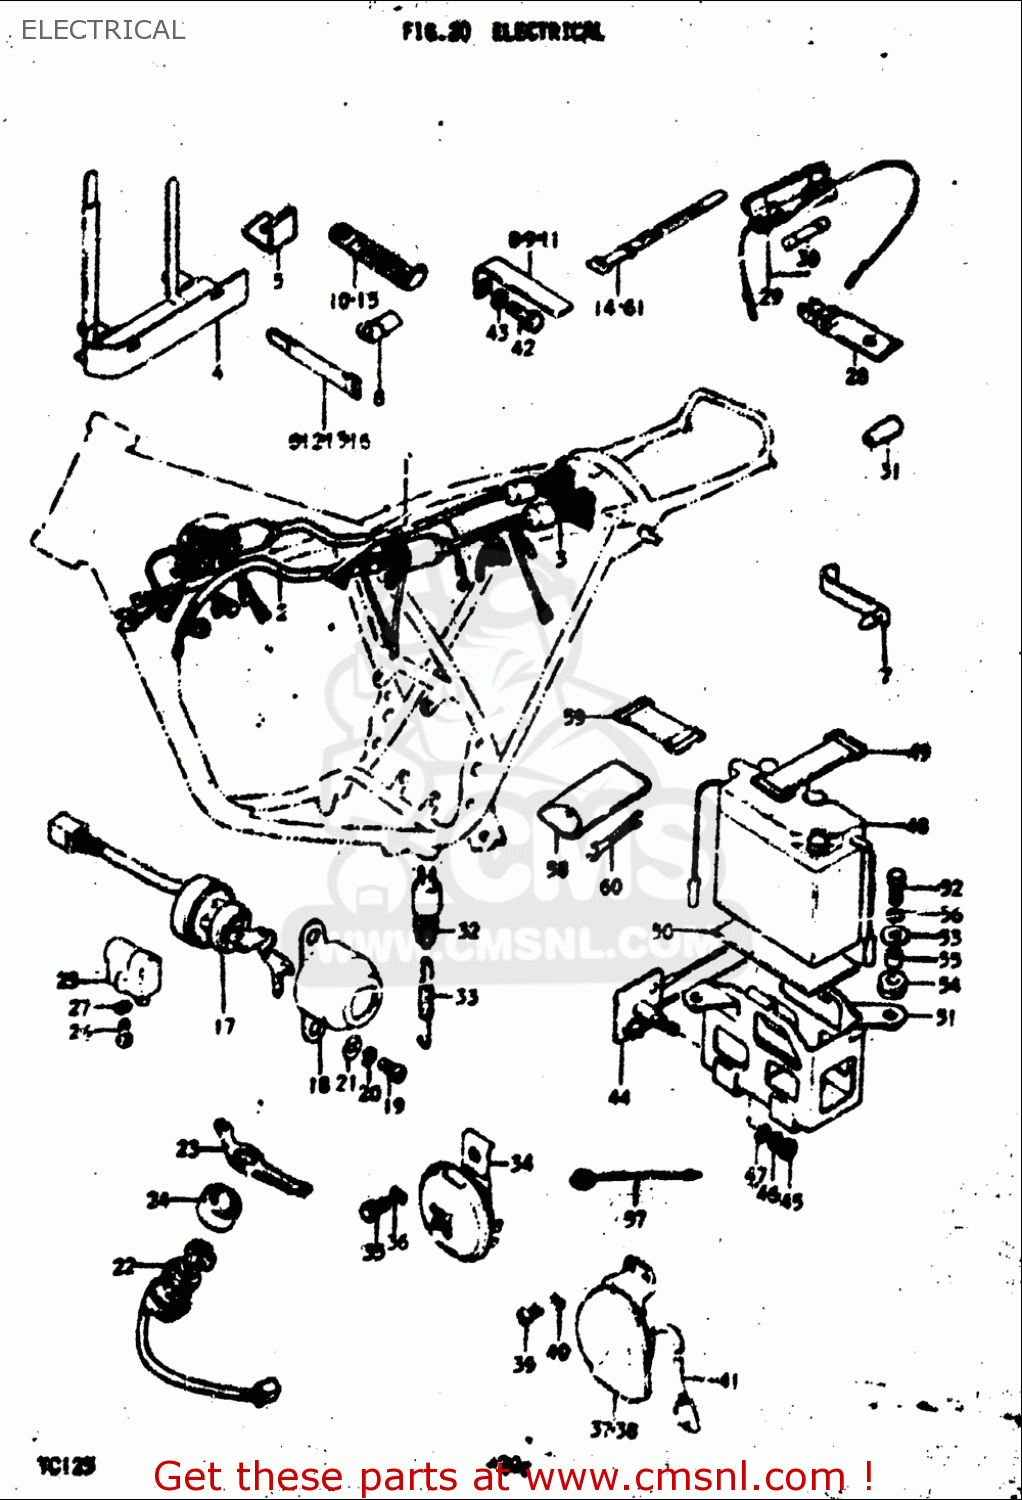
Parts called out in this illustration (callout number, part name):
1	RELAY ASSY,TURNSIGNAL
9	CLAMP
10	CLAMP(L:80 T:1.0)
12	CLAMP
13	CLAMP
14	CLAMP(L:120)
15	CLAMP(L:65)
16	CLAMP(L:250)
19	SCREW
20	WASHER,LOCK
21	WASHER
22	SWITCH ASSY,IGNITION
25	LOCK ASSY,STEERING
26	SCREW
27	WASHER,LOCK
29	CASE ASSY,FUSE
30	FUSE(15A)
32	SWITCH ASSY,BRAKE LAMP
33	SPRING
35	BOLT
36	WASHER,LOCK
39	SCREW
40	WASHER,LOCK
41	WIRE
42	BOLT
43	WASHER,LOCK
45	NUT
46	WASHER,LOCK
47	WASHER
48	BATTERY(6N4B-2A,6V4.2AH)
49	BAND
52	BOLT
53	WASHER(6.5X20X1.2)
54	CUSHION
55	SPACER,6.5X9X7
56	WASHER,LOCK
57	LEAD WIRE
58	TOOL ASSY
59	BAND
